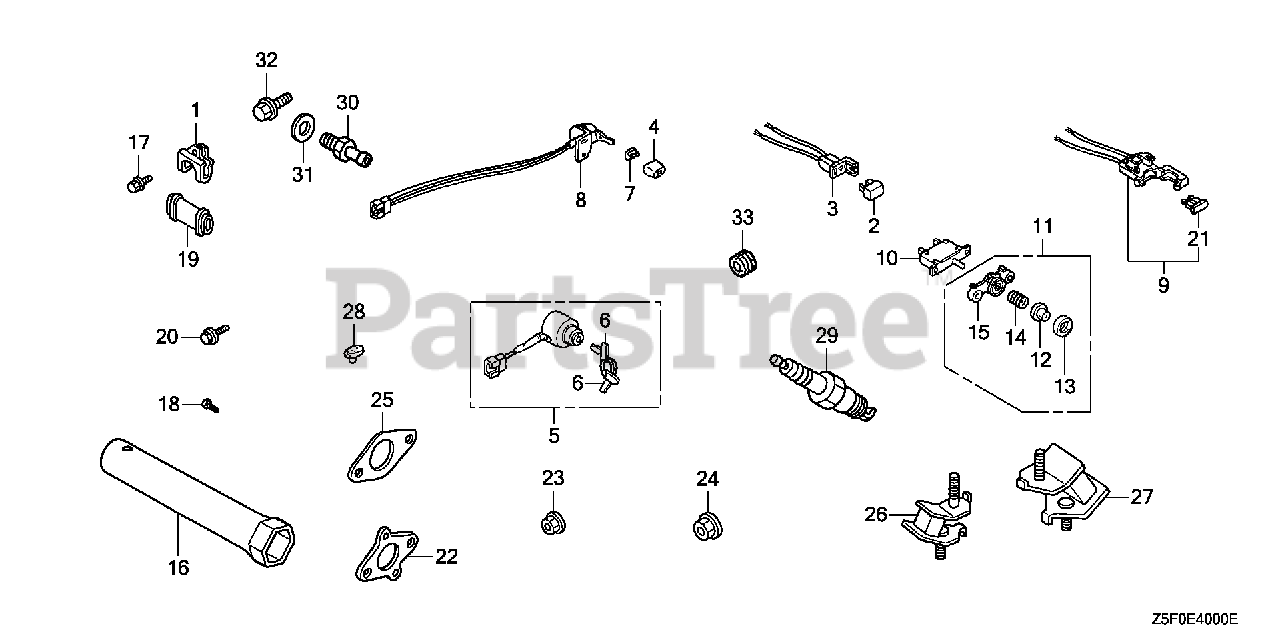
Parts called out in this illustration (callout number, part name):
22	GASKET, EX. PIPE
23	NUT, FLANGE (6MM)
24	NUT, FLANGE (8MM)
